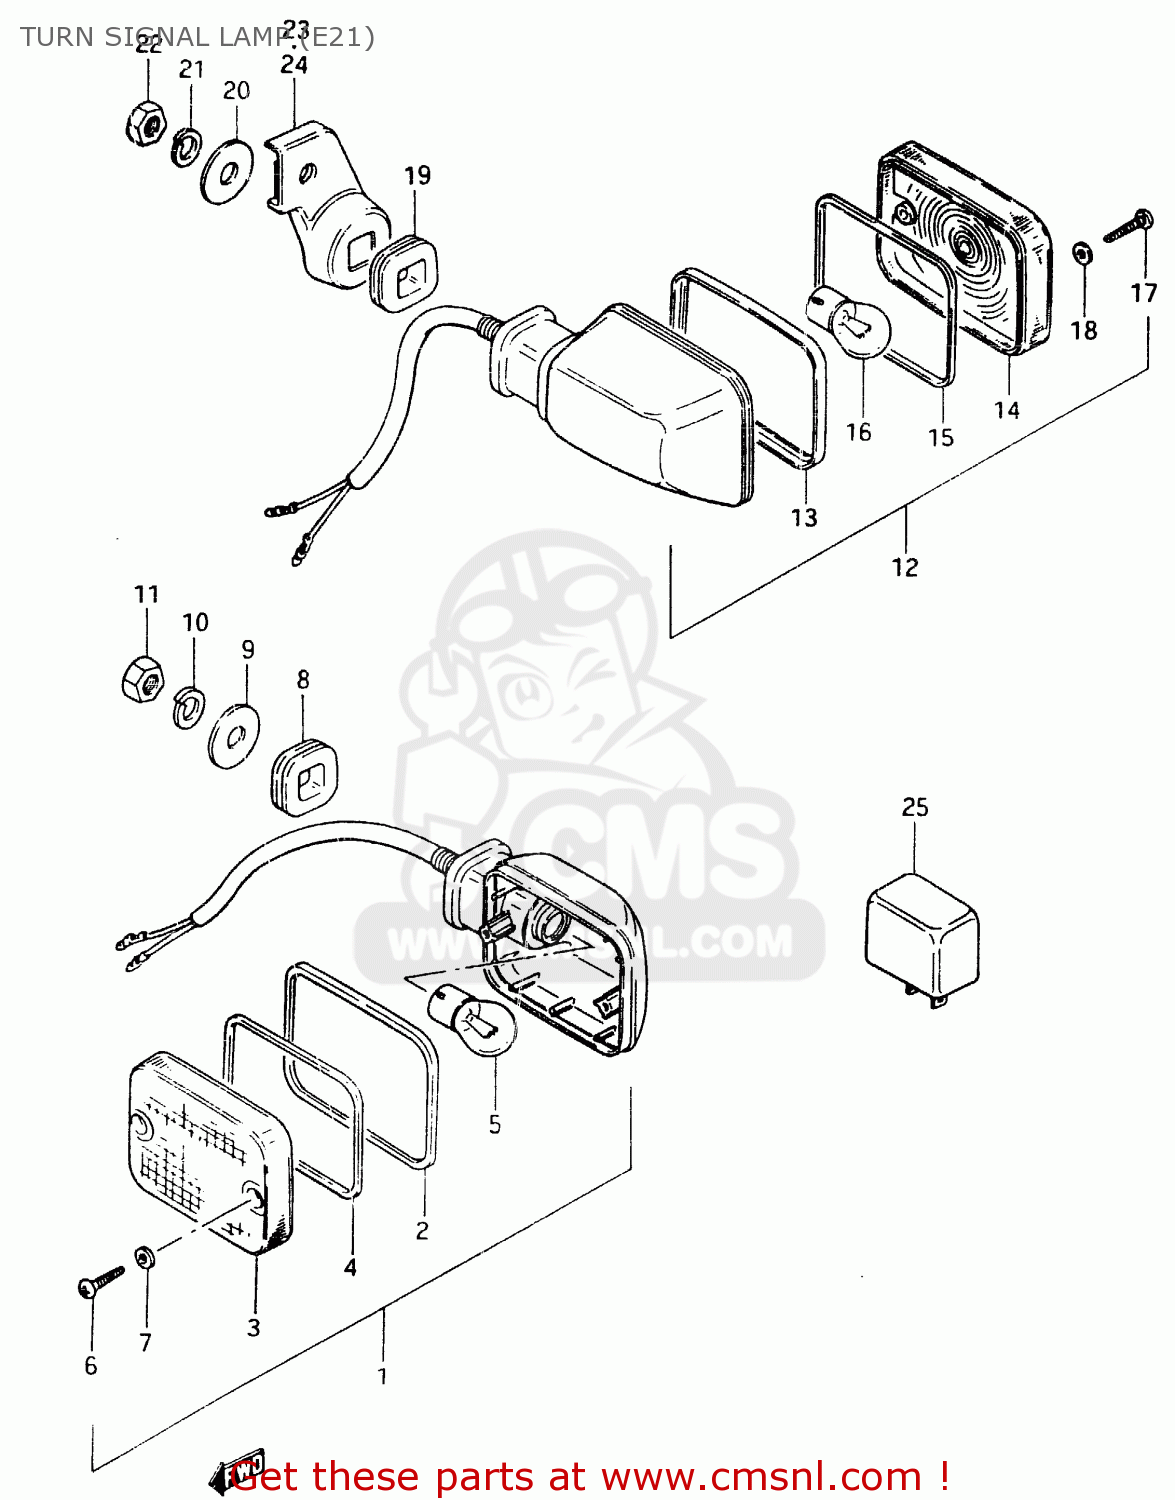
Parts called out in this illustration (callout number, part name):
1	LAMP ASSY,FR T
2	RIM
3	LENS
4	GASKET (NAS)
5	BULB(12V21W)
6	SCREW
7	GASKET (NAS)
8	CUSHION
9	WASHER (10.5X30X2.3)
10	LOCK WASHER
11	NUT
12	LAMP, REAR TURN SIGNAL
13	RIM
14	LENS
15	GASKET (NAS)
16	BULB(12V21W)
17	SCREW
18	GASKET (NAS)
19	CUSHION
20	WASHER (10.5X30X2.3)
21	LOCK WASHER
22	NUT
23	BRACKET,REAR TURN SIGNAL
24	BRACKET,REAR TURN SIGNAL
25	RELAY,TURN SIGNAL
